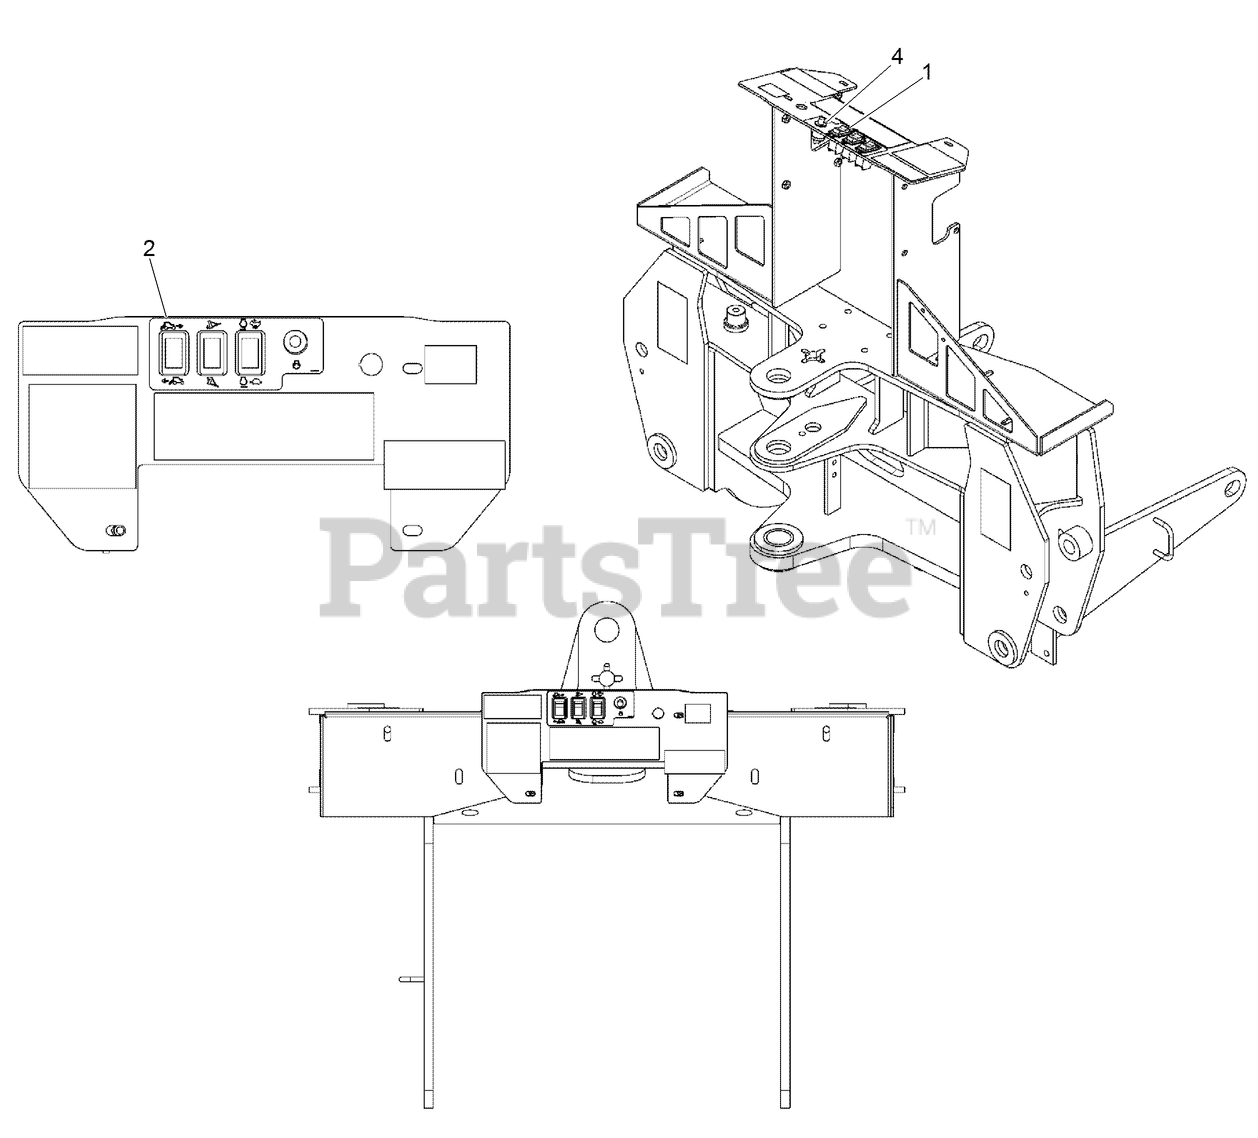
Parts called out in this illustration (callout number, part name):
1	SWITCH-ROCKER, 2 POLE
2	DECAL - Backhoe Controls
4	SWITCH - Pushbutton
